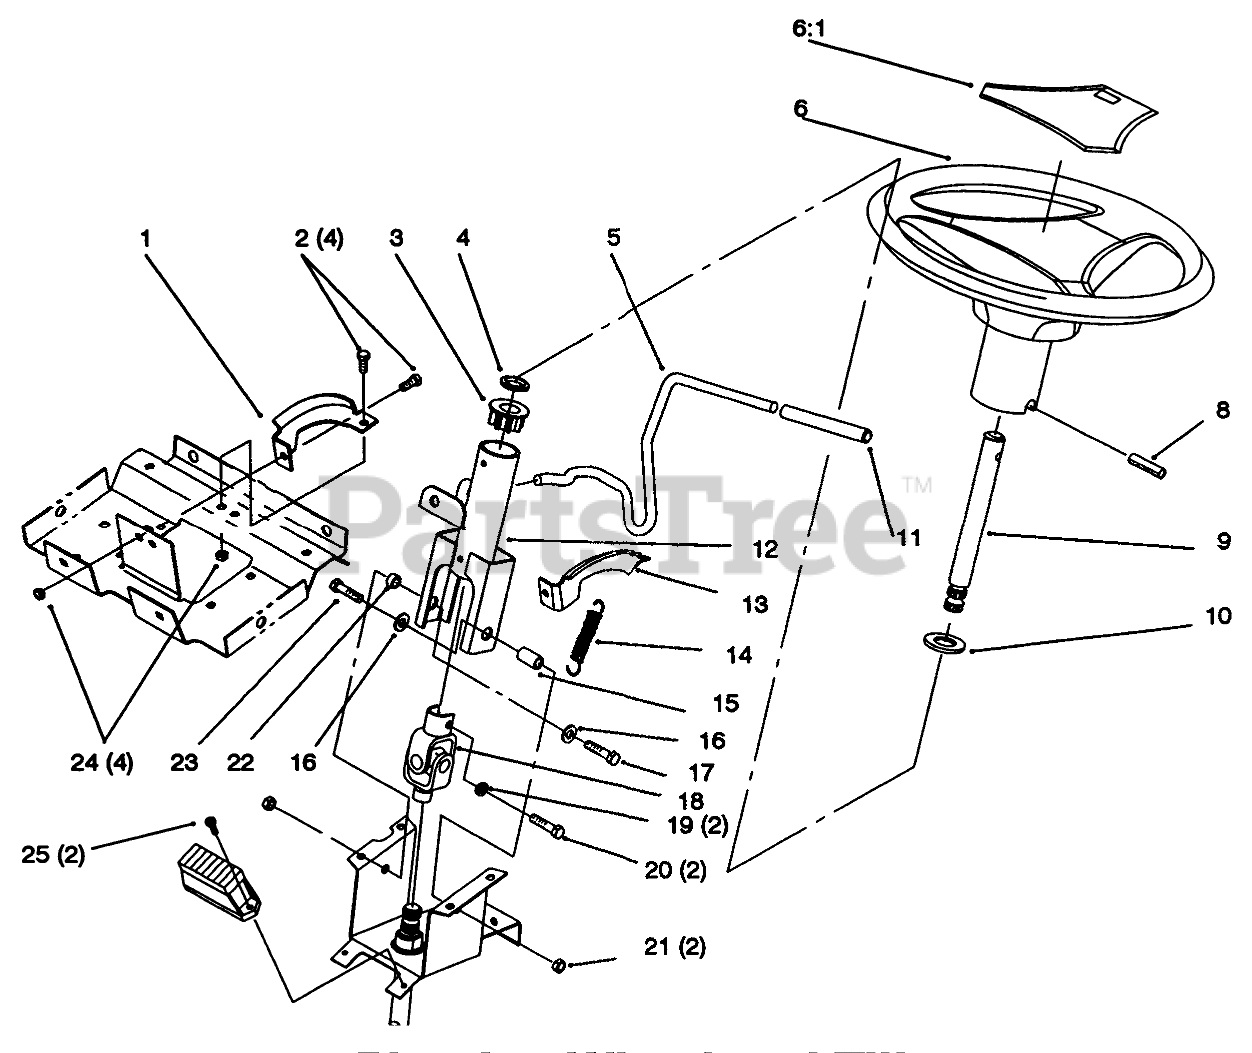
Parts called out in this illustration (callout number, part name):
1	BRACKET-SUPPORT, COLUMN
2	SCREW-HH
3	BUSHING-STEERING, UPPER
4	WASHER-BOWED
5	LEVER-TILT
6	Steering Wheel (Only On: 72042, 72062, 72043)
6	Steering Wheel (Only On: 72063, 72083, 72103)
6:1	Cover-Steering Wheel (Only On: 72063, 72062, 72083, 72043, 72103)
8	PIN-ROLL
9	SHORT UPPER STRG SHAFT
10	WASHER-FLAT
11	CAP-ROD, TILT
12	COLUMN ASM
13	BRACKET-DETENT
14	SPRING-EXTENSION
15	SPACER-YOKE
16	WASHER-PLAIN
17	SCREW-HH
18	U-JOINT, STEERING
19	WASHER-LOCK
20	SCREW-CAP, HH
21	NUT-LOCK, NI
22	SPACER-YOKE, RIGHT
23	SCREW-HH
24	NUT-HEX
25	SCREW-PPHTF
